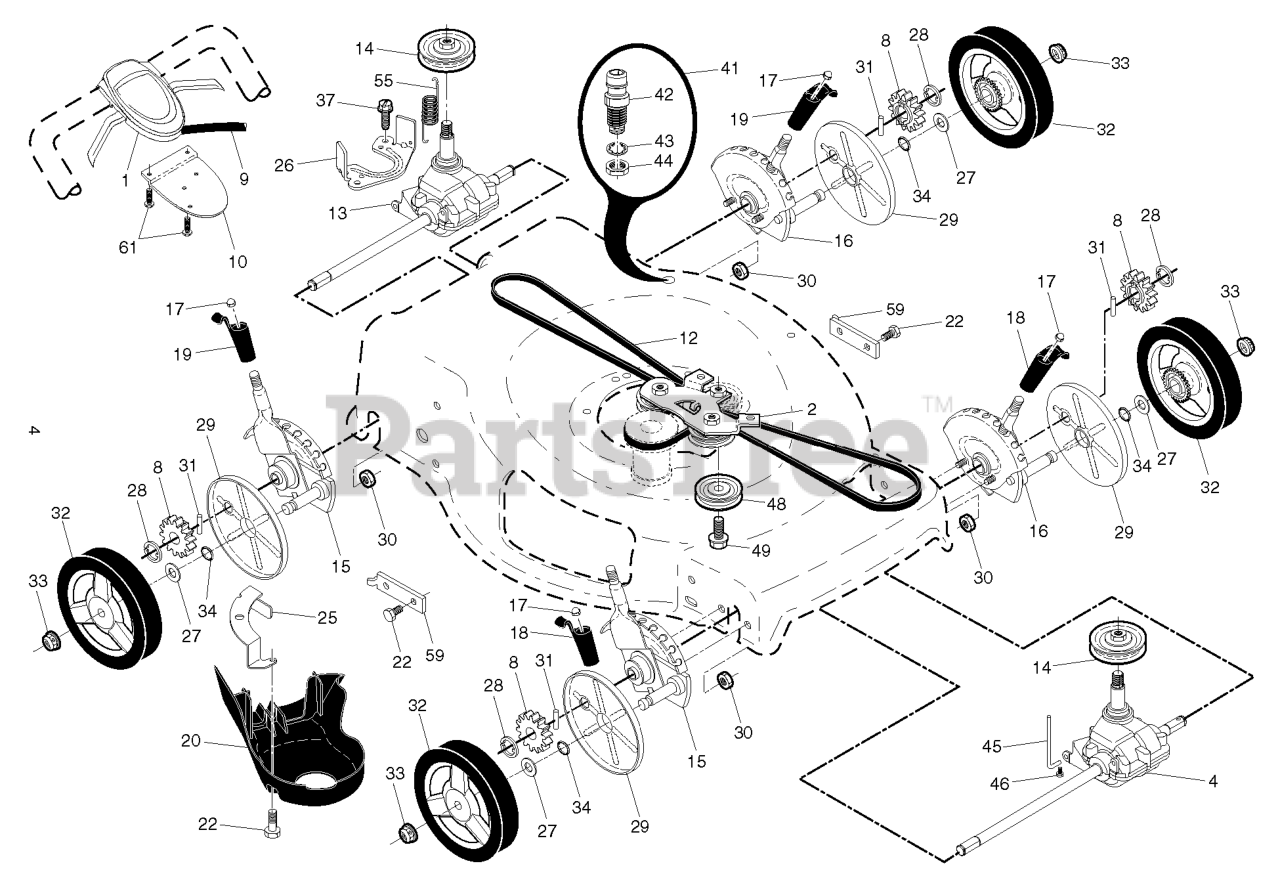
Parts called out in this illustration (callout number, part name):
1	CONTROL.AW2.22+RG.BS.GEN.BK/BK
2	BRACKET.TRAN.BELTKEEPER.22+RGD
4	RP.TRANSMISSION.22+.AWD.FRONT
8	PINIION.14.TOOTH.RGD
9	CABLE.DRIVE.RWD.WALK.
10	BRACKET.DRIVE.CONTR.GEN2.BLACK
12	BELT.DRIVE.AWD.13 ZINC DUSTED
13	TRANMISSION.ASM.22+AWD.REAR.14
14	RP PULLEY.PM.22+AWD
15	KIT.ADJ.22+QP.RT F/R.BLK.
16	KIT.ADJ.AWD.22+LT.F/R.BLK
17	NUT.PUSH.156
18	KNOB.ADJUSTER.LW.BLK
19	KNOB.ADJUSTER.REAR.BLACK
20	COVER.REAR.DRIVE.22+2013
22	BOLT.5/16HEX.WHS.HD
25	BRACKET.DRIVE.COVER.RGD.BZP
26	BRACKET.TRAN.BELTKEEPER.22+RGD
27	WASHER FLUT
28	E-RING 7/16 RE
29	COVER.DUST.WHEEL.INNER.WALK
30	NUT.FLANGE.1-4-20-SERR
31	PAWL, DRIVE
32	WHEEL.8".AWD.3SP.EXT.DR.GREY
33	NUT.HEX.FLANGE.3/8-16.LO(3 2)
34	O-RING..070X.487.NEOPRENE
37	SCREW.HX.13X.750
41	KIT.WASH-OUT.PORT
42	FITTING, HOSE, WATER WASHOUT
43	WASHER.LOCK.INTERNAL.TOOTH
44	LOCKNUT.HEX.WITH.O-RING
45	BRACKET.AWD.FRONT.BELT.KEEPER
46	SCREW.HI-LO. 5/16 X 1.00
48	RP PULLEY.IDLER.ASM
55	SPRING.RETURN.AUTO.
59	BRACKET.SUPPORT.22+RWGD.BZP
61	SCREW, PHILLIPS HEAD 10 X 5/8
